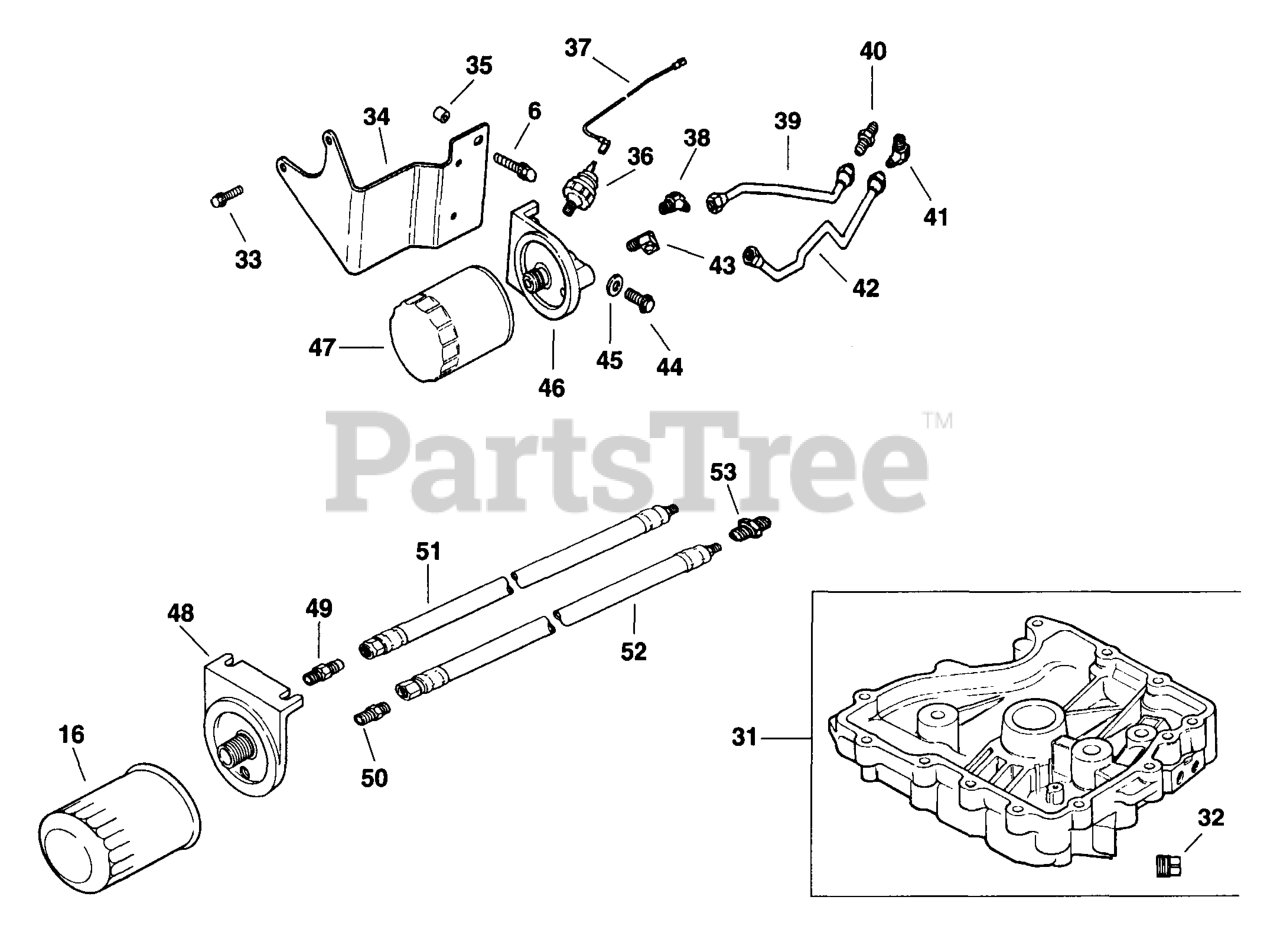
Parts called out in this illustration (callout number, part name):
6	Screw, Hex. Flange M5x0.8x20
16	Filter, Oil
36	Switch, Oil Pressure
37	Lead, Green
